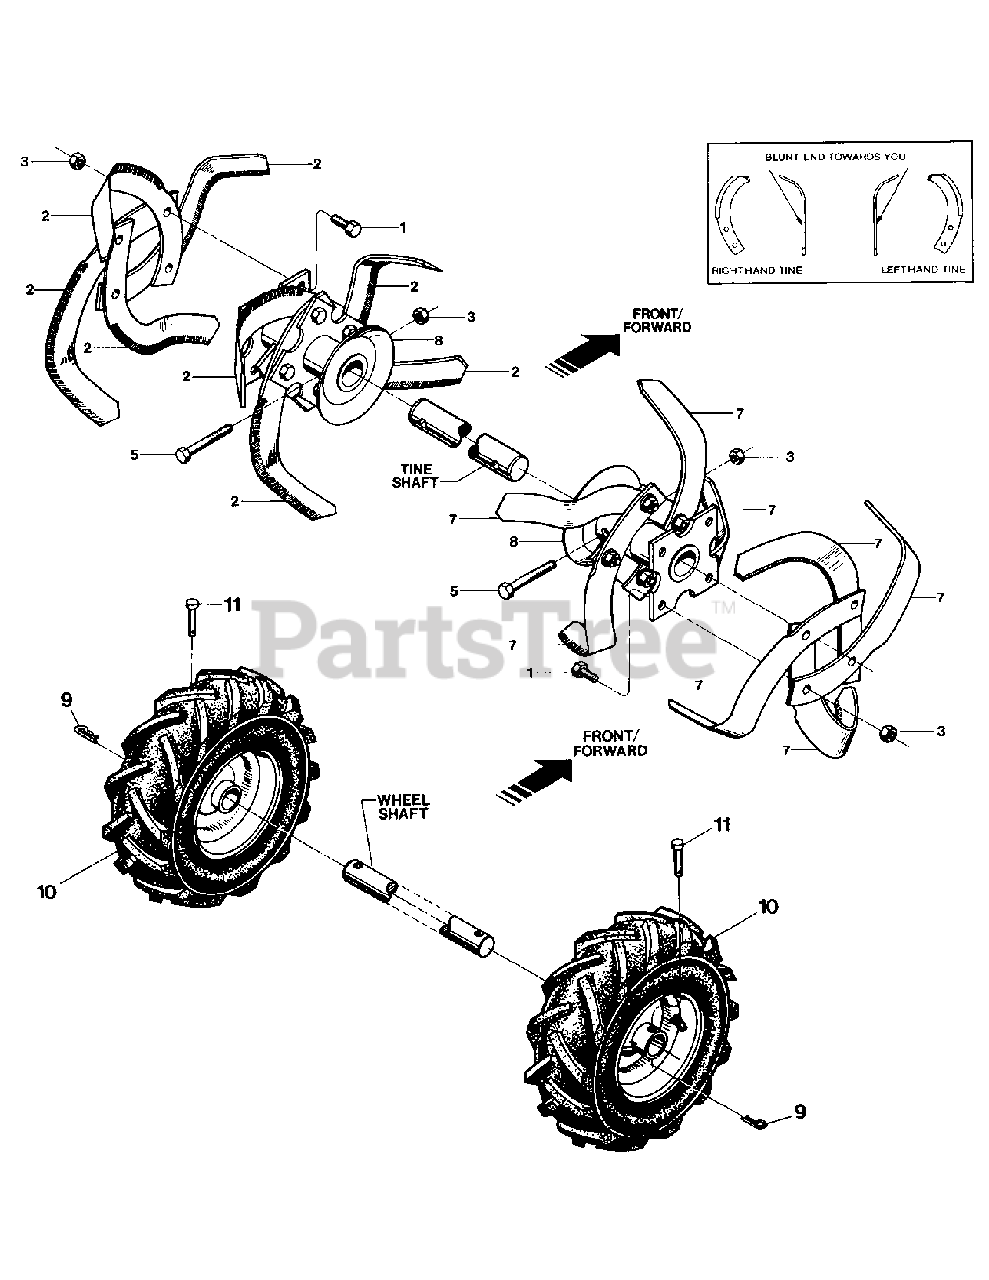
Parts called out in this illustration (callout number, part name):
1	Hex Hd. Screw, 3/8-16 x 1 GRADE 5
2	Bolo Tine-single. Left
3	Hex Locknut, 3/8-16
5	Hex Hd. Screw, 3/8-16 x 2, Grade 8
7	Bolo Tine-single. Right
8	Tine Holder. For left and right sides
9	Hitch Pin
10	Wheel and Tire Assembly
11	Clevis Pin, .312 x 1-3/
